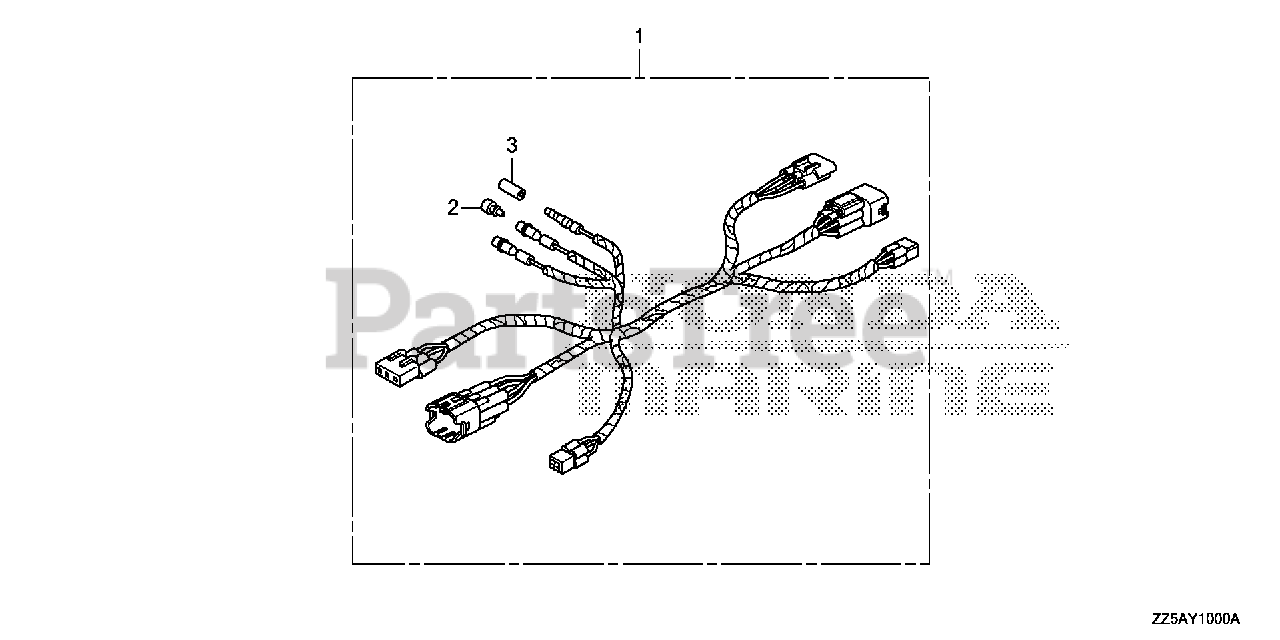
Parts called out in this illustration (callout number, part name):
1	HARNESS ASSY., REMOTE CONTROL SUB (ENGINE NO.)
2	PLUG, CONNECTOR (INNER) (ENGINE NO.)
3	PLUG, CONNECTOR (OUTER) (ENGINE NO.)
